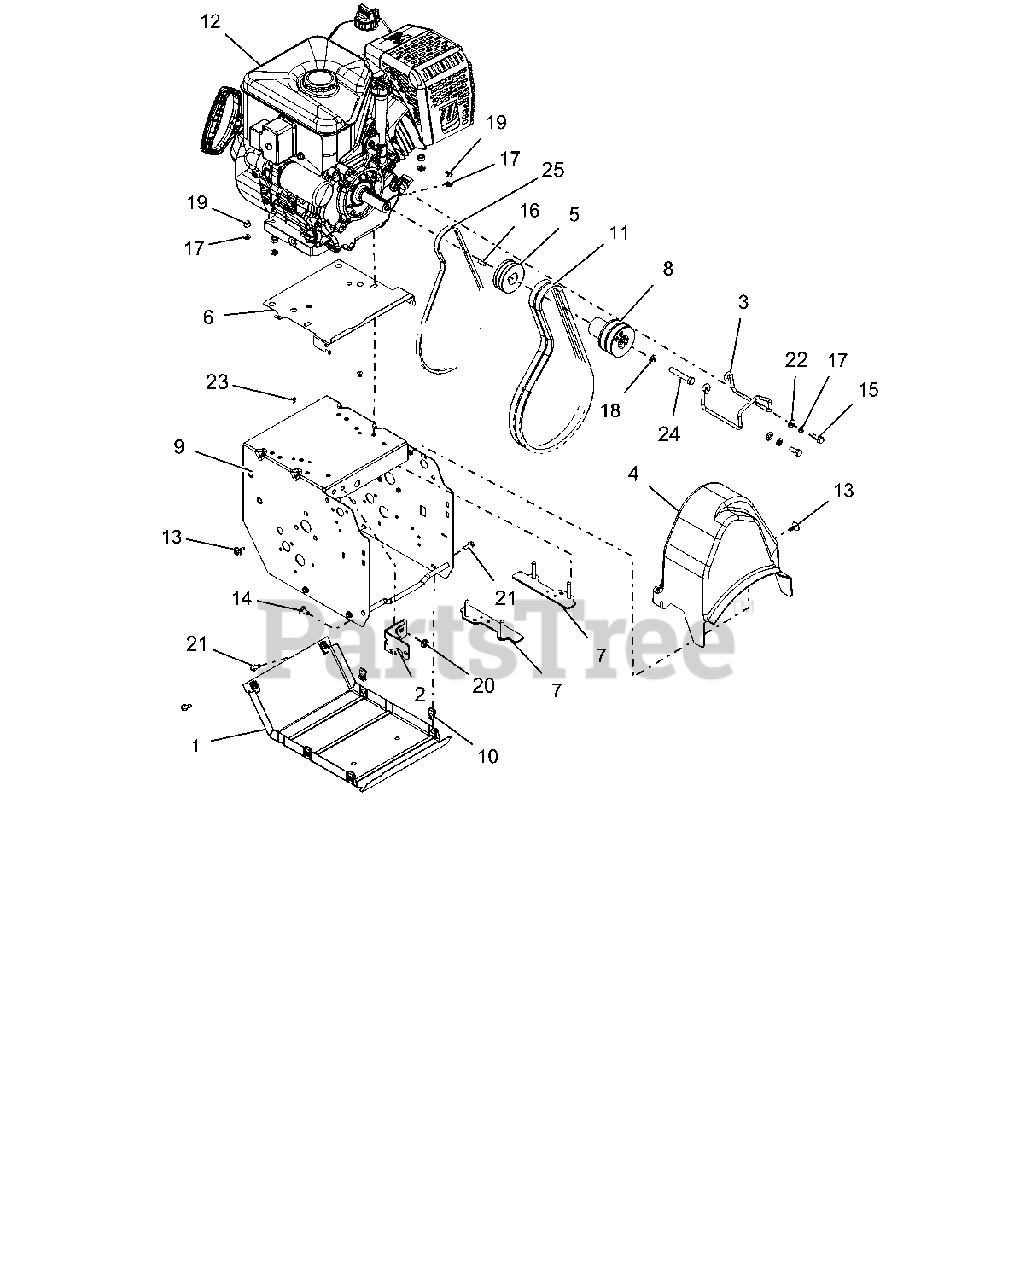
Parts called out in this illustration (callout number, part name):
1	COVER, BOTTOM
2	WELDMENT, FRAME BRACKET
3	FINGER, BELT
4	BELT COVER
5	SHEAVE DRIVE
6	BAFFLE,ENGINE,ARIENS LRG BLOCK
7	STRAP,ENGINE BOLT,ARIENS LRG
8	SHEAVE,ATTACHMENT 2-GRV
9	FRAME, MAIN-WELDMENT
10	NUT-RTNR .25-20X.56
11	V-BELT, HA-RAW EDGE (SET)
12	ENGINE, AX369 GEN 3 120V/60W
13	SCR-TAP .25-20X.5 CAPTIVE
14	@BLT-RHDSSQNK .31-18X.62 G5YZ
15	BLT-HEX .31-24X.75 YWZC GR5
16	KEY-SQ .25X.625X.25 SAE 8630
17	WSHR-LK .312X.097 HVY YWZC
18	@WSHR-LK .38X.094 REG YWZC
19	@NUT-HEX .31-18 YWZC
20	@NUT-LK-TOP-FLG .31-18 YWZC
21	BLT-HEX .25-20X.75 HWH YZ GR5
22	@WSHR-FL-STL.344X.688X.065YWZC
23	RVT-POP .187 YZ
24	BLT-HEX .38-24X2.25 YWZC GR5
25	V-BELT, 3L-WRAPPED
